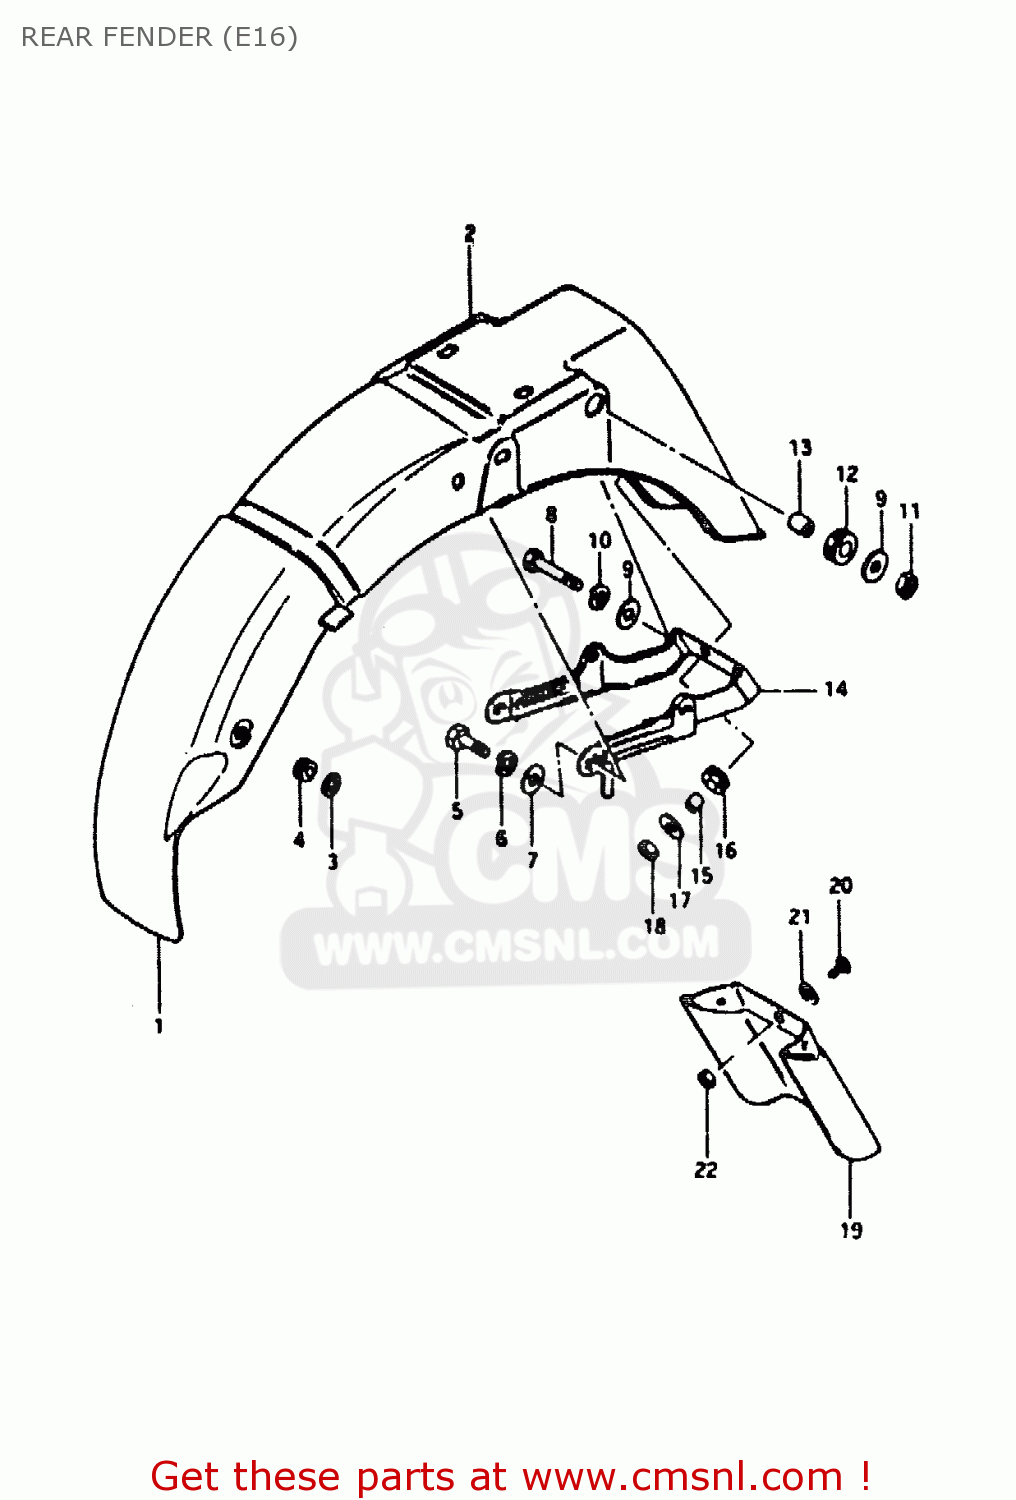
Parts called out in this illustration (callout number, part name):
1	BODY, REAR FENDER FRONT
2	FENDER, REAR
3	WASHER
4	CUSHION
5	BOLT, UPPER
6	LOCK WASHER
7	WASHER
8	BOLT
9	WASHER
10	LOCK WASHER
11	NUT
12	CUSHION
13	SPACER (8.2X12X7.5)
14	REINFORCEMENT
15	SPACER (6.1X9X9)
16	CUSHION
17	WASHER(6,5X22X1.6)
18	NUT
19	MUD GUARD
20	SCREW
21	WASHER
22	NUT
